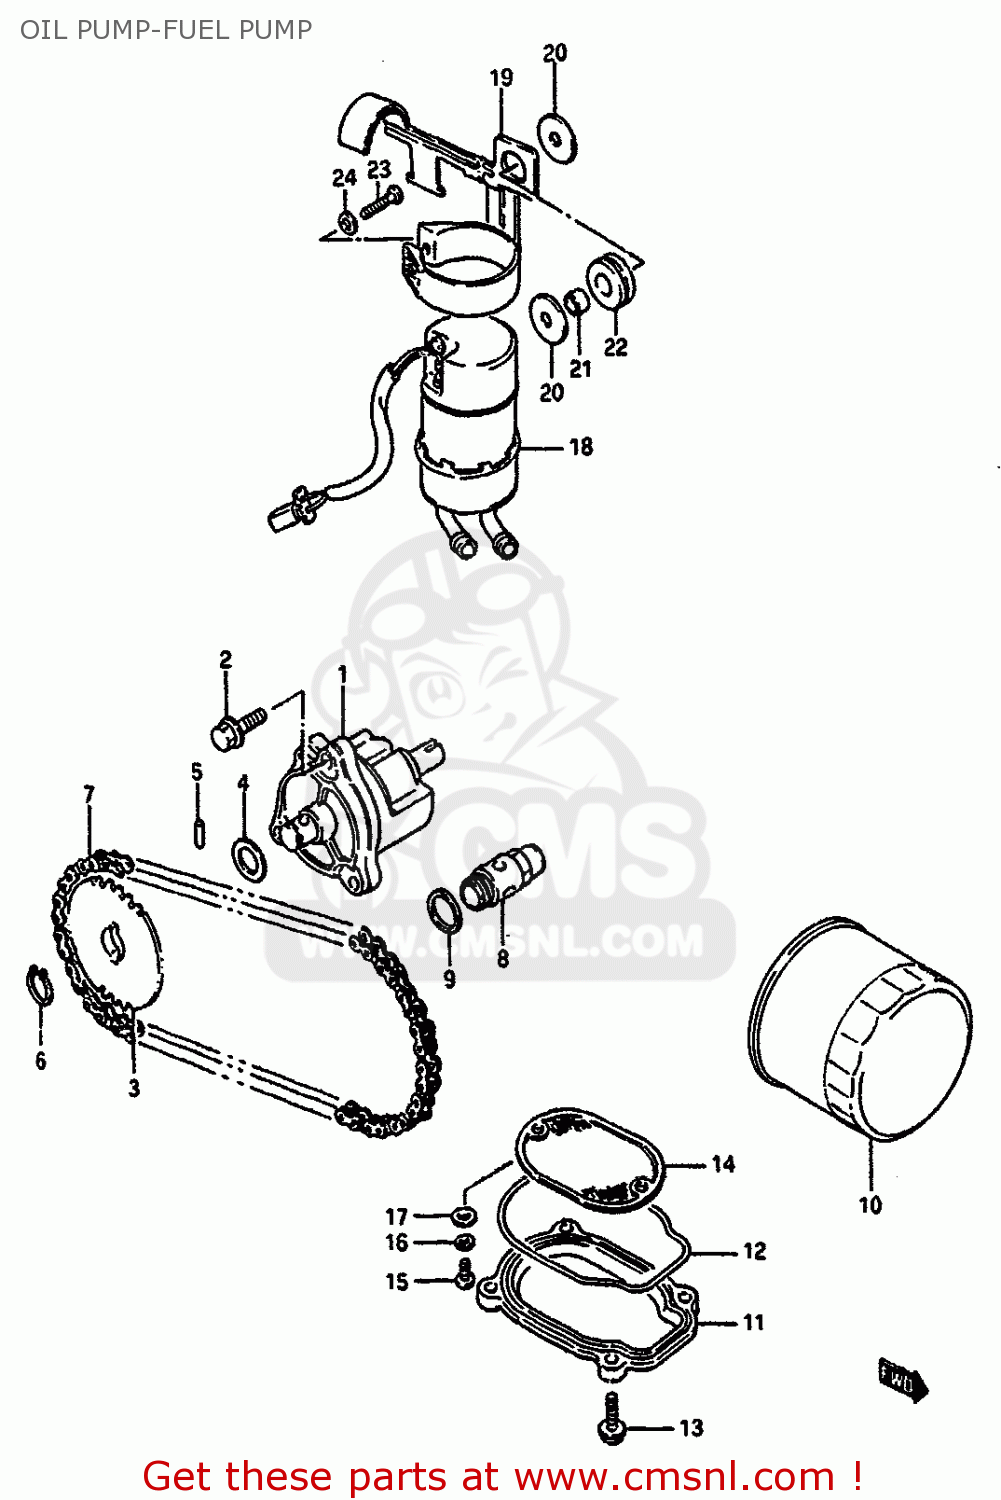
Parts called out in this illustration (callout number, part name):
1	PUMP ASSY,ENGINE OIL
2	BOLT 6X25
3	SPROCKET,OIL PUMP DRIVEN
4	SHIM
5	PIN(5X18)
6	CIRCLIP
7	CHAIN,OIL PUMP DRIVE
8	VALVE ASSY,OIL RELIEF
9	GASKET(16X22X2) (NAS)
10	FILTER ASSY,ENGINE OIL
11	CAP,OIL STRAINER
12	O RING,OIL STRAINER CAP
13	BOLT 6X20
14	STRAINER,ENGINE OIL
15	SCREW 5X12
16	LOCK WASHER
17	WASHER
18	PUMP ASSY,FUEL
19	BRACKET,FUEL PUMP
20	WASHER (6.5X24X1.6)
21	SPACER(6.5X10.5X6.5)
22	CUSHION
23	SCREW
24	WASHER 4MM
